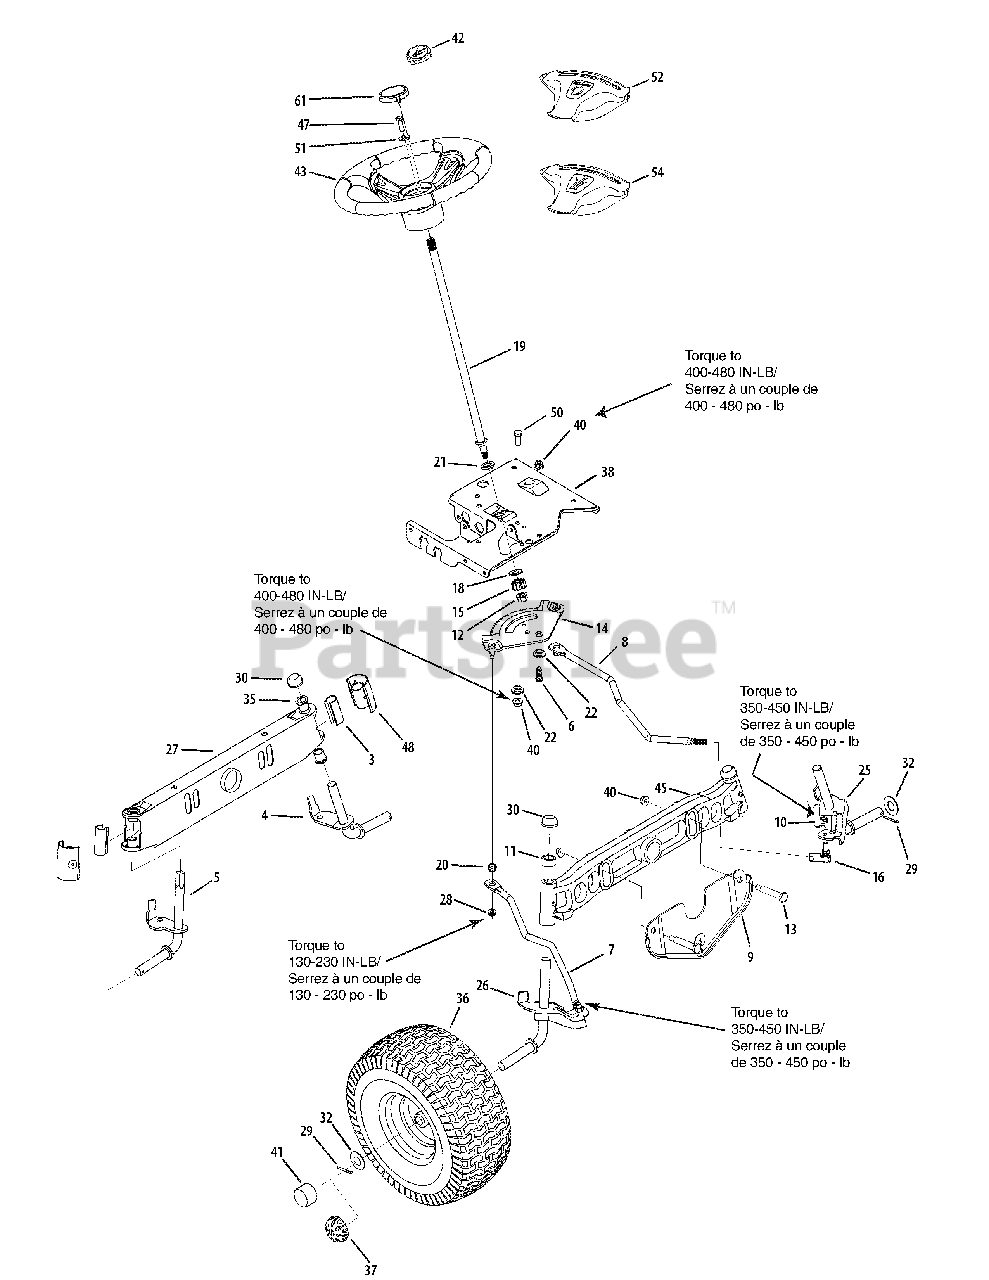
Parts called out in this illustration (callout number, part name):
4	LH Axle Assembly, .750 Dia. 42" Deck
5	RH Axle Assembly, 750 Dia. 42" Deck
6	Hex Cap Screw 3/8-16 x 1.00 Gr. 5 Spec.
7	RH Drag Link
10	Hex Cent. L-Nut 3/8-24
11	Spacer .71 ID x .125 OD x .56" Lg.
12	Flange Lock Nut, 7/16-20
13	Shoulder Bolt .50 x 2.38: 3/8-16
14	Steering Gear, 11/90 Ratio
15	Steering Pinion Gear
16	Ball Joint, 7/16 - 20
18	Fl. Washer .510 x 1.120 x .060
19	Steering Shaft, .625 OD x 24.25
20	Plastic Bushing .380 ID
21	Hex Flange Bearing, 5/8
22	Shoulder Spacer
25	LH Axle Assembly, .750 Dia.
26	RH Axle Assembly, .750 Dia.
28	Hex Flange L-Nut 5/16-18 Gr. 5
29	Cotter Pin 5/32" Dia. x 1.25
30	Push Cap, .750
32	Flat Washer .780 ID X 1.56 OD
32	Flat Washer .781 ID x 1.90 OD
34	Shoulder Screw, .5 x 2.2, 3/8-16
35	Flange Bearing .760 ID x .937 OD
37	Hub Cap
38	Steering Support Bracket
39	Shld. Scr. .500 Dia. X .335" Lg.
40	Hex Flange L-Nut 3/8-16 Gr. F
42	Steering Wheel Cap - Small w/logo
43	Steering Wheel - 3 Spokes Std. Grip
43	Steering Wheel - 3 Spokes Soft Grip
44	Plastic Hub Cap
45	Cast Iron Pivot Bar (.750 dia.)
47	Hex Screw 5/16-18 X 1.00 Special
48	Pivot Bar End Cap
50	Hex Screw 3/16 x 1.00
51	Flat Washer .406 ID x .875 OD x .105
52	Steering Wheel Cover - Troy Bilt
53	Hex Wash HD AB Tap Scr 5/16-12 x .75
54	Steering Wheel Cover - MTD
56	Steering Wheel Cap
57	Steering Wheel - Soft Grip
61	Steering Wheel Cap - Small w/o logo
